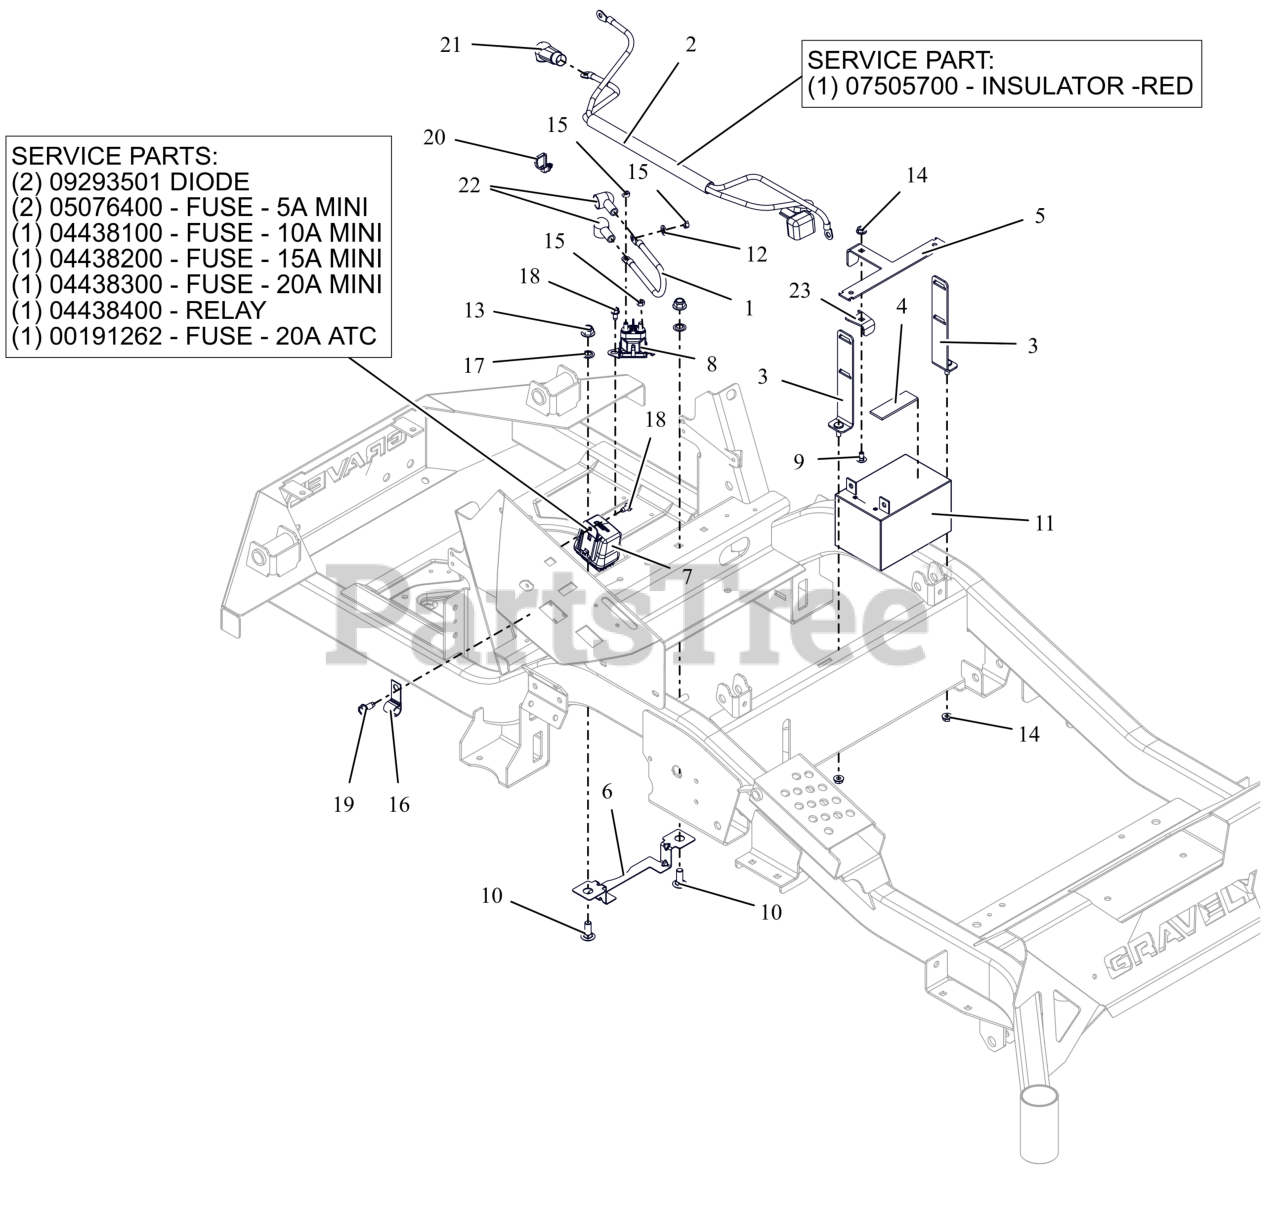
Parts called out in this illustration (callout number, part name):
1	CABLE, POS W/(2)1/4 RING 9.0LG
2	HARNESS, BATTERY HD
2	INSULATOR
3	WMT,BATTERY MOUNT HOLD DOWN
4	PAD,RBR 1.0"X3.0" W/ADHESIVE
5	BRKT, BATTERY TIE DOWN
6	GUARD, ELECTRICAL HARNESS
7	HARNESS, WIRE
7	DIODE, CONNECTOR SHELL
7	FUSE, 5 AMP MINI-ATC
7	FUSE,10 AMP MINI-ATC
7	FUSE,15 AMP MINI-ATC
7	FUSE,20 AMP MINI ATC
7	RELAY,MICRO5 TERML W/RESISTOR
7	FUSE, 20 AMP BLADE S/O
8	SOLENOID, STARTER (SEALED)
9	BLT, RHSN .25-20X.500 G5 ZCC
10	BLT, RHSN .38-16X1.00 G5 ZCC
11	BATTERY, 12V 12A -190CCA
12	WSHR,LK-REG .312X.078 ZCC
13	NUT,NYL-FLG .38-16 GF ZCC
14	NUT-LK-TOP-FLG .250-20 GF ZCC
15	NUT-STD M6-1.0 ZCC
17	NUT-PUSH .38 DIA. PAL ZINC
18	SCR-TAP .25-20X.50 HWH ZCC
19	SCR,TAP .312-18X.75 HWH TR ZCC
20	CABLE TIE W/ TREE (.25 HOLE)
21	BOOT, .65ID POS
22	BOOT, EYELET TERMINAL
23	BRKT, BATTERY HOLD
